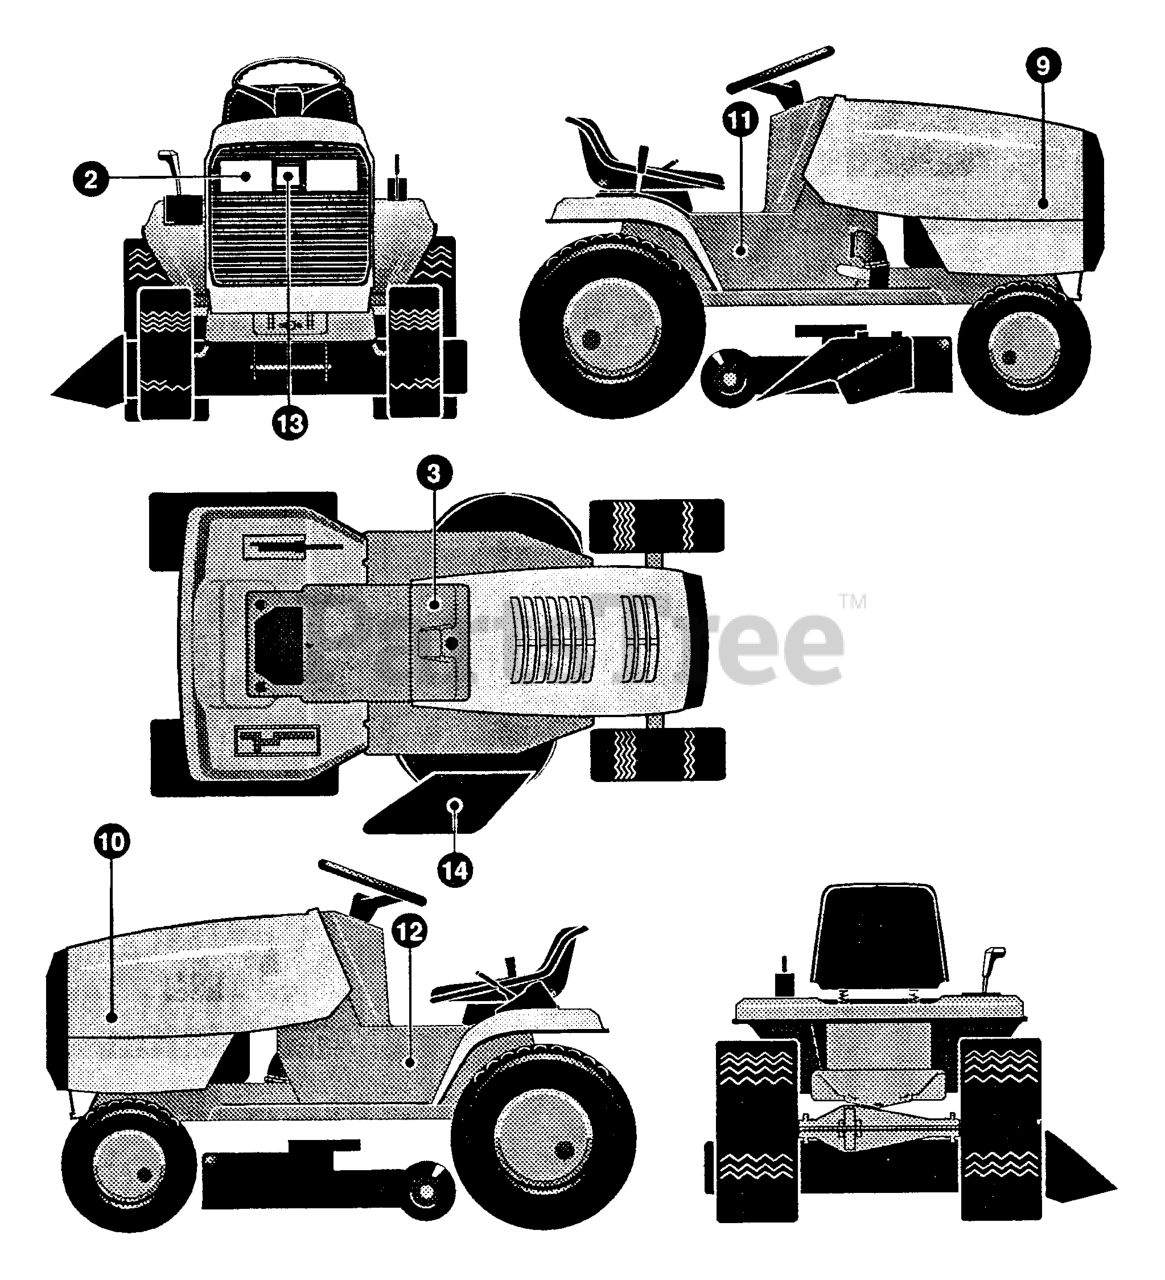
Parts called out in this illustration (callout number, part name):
2	REFLECTOR
9	18 HP HOOD (RH)
10	18 HP HOOD (LH)
11	43" CONSOLE (RH)
12	43" CONSOLE (LH)
13	GRILLE INSERT
14	MULCH KIT INSTAL
